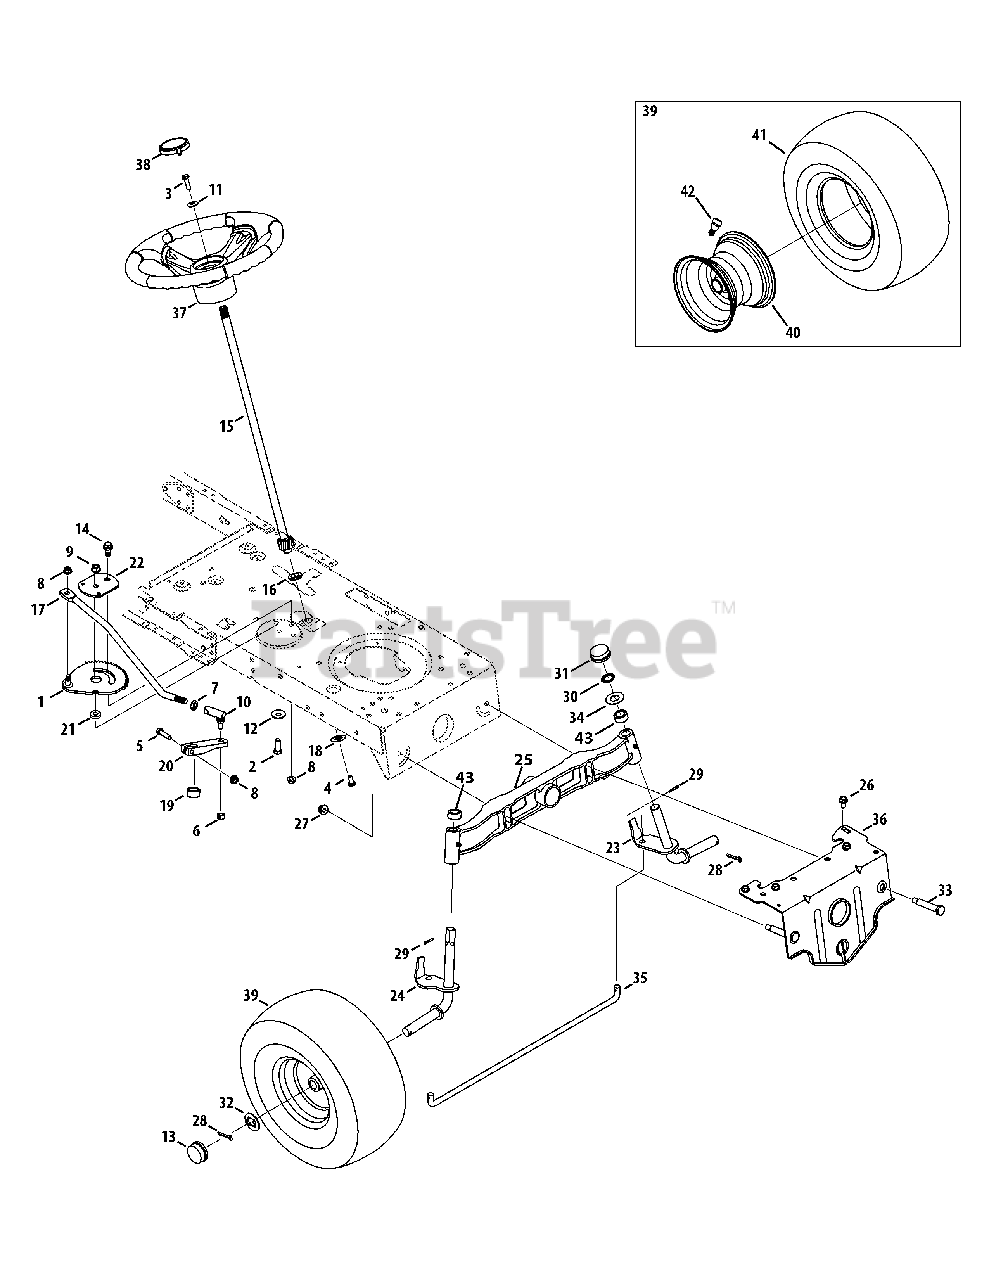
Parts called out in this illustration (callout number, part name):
1	Gear Assembly, Steering
2	Hex Head Screw, 3/8-16 x 1.00
3	Screw, 5/16-18, 1.00, Gr5, Lock
4	Screw, Mach, 5/16-18, 0.750
5	Screw, 5/16-18, 1.75, Gr5
6	Nut, Jam Lock, 3/8-24
7	Nut, Jam, 7/16-20, Gr2
8	Nut, Flange Lock, 5/16-18, Grf
9	Nut, Flange Lock, 3/8-16, Grf
10	Ball Joint, 7/16-20, Lock
11	Washer, Bell, .340 x .872 x .060
12	Bevel Washer, .390 x 1.130 x .062
13	Hub Cap
14	Shoulder Screw, 5/16-18
15	Steering Shaft, 5/8 Spline
16	Bearing, Flange, Hex 5/8
17	Drag Link, Steering
18	Cap, 1.25 x .16
19	Spacer, .710 ID x .125 OD x .56
20	Steering, Block
21	Spacer, .38 x .854 x .20
22	Stabilizer Gear Plate
23	Axle Assembly LH
24	Axle Assembly RH
25	Pivot Axle, Cast
26	Screw, 5/16-18, 0.750
27	Nut, Flange Lock, 3/8-16, GrF
28	Pin, Cotter, 5/32, 1.25
29	Pin, Cotter, 1/8 x 0.75
30	Push Nut, 3/4
31	Hub Cap
32	Washer, Flat, .781 x 1.59
33	Screw, Shlder, .500 x 2.380, 3/8-16
34	Flat Washer, .78 x 1.59 x .060
35	Tie Rod
36	Pivot Bar Bracket
37	Steering Wheel, Softgrip
38	Cap, Steering Wheel (Crafts. logo)
39	Wheel Assembly
41	Tire, 15 x 6 x 6 Rd. Shoulder
42	Valve Stem
43	Spacer, .71 x .125 x .56
